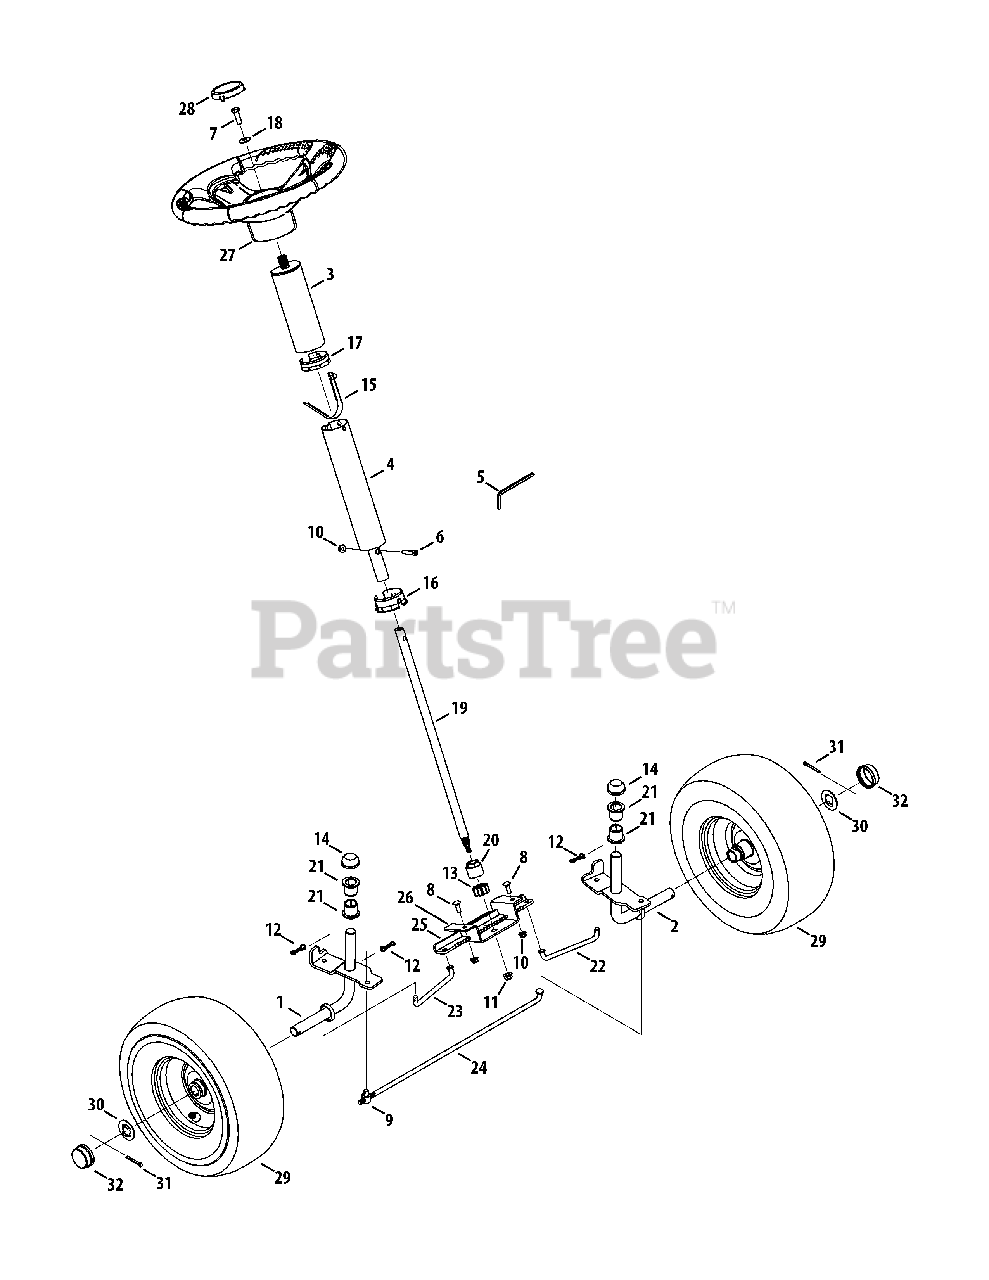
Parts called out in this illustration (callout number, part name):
1	Front Axle Assembly, RH
2	Front Axle Assembly, LH
3	Upper Tube Assembly
4	Lower Tube Assembly
5	Allen Wrench, 3/16
6	Screw, 1/4-20 X 1.25
7	Hex Head Screw, 5/16-18x1.00
8	Carriage Screw, 1/4-20x.75
9	Ferrule, 5/16-24 X .312 Dia.
10	Flange Lock Nut, 1/4-20
11	Flange Lock Nut, 3/8-16
12	Bow-Tie Cotter Pin
13	Steering Pinion Gear
14	Push Cap, 3/4
15	Snap Butt
16	Lower Steering Collar
17	Upper Steering Collar
18	Bevel Washer, .340X.872X.060
19	Steering Shaft, .625 OD X 18.03
20	Hex Flange Bearing, 5/8
21	Flange Bearing, .760 X .941 X 1.0
22	Steering Rod, LH
23	Steering Rod, RH
24	Front Tie Rod
25	Steering Rack Plate
26	Lower Steering Bracket
27	Steering Wheel
28	Steering Cap
29	Complete Wheel Assembly
30	Washer, .781 x 1.59
31	Cotter Pin, 5/32 x 1.25
32	Hub Cap
